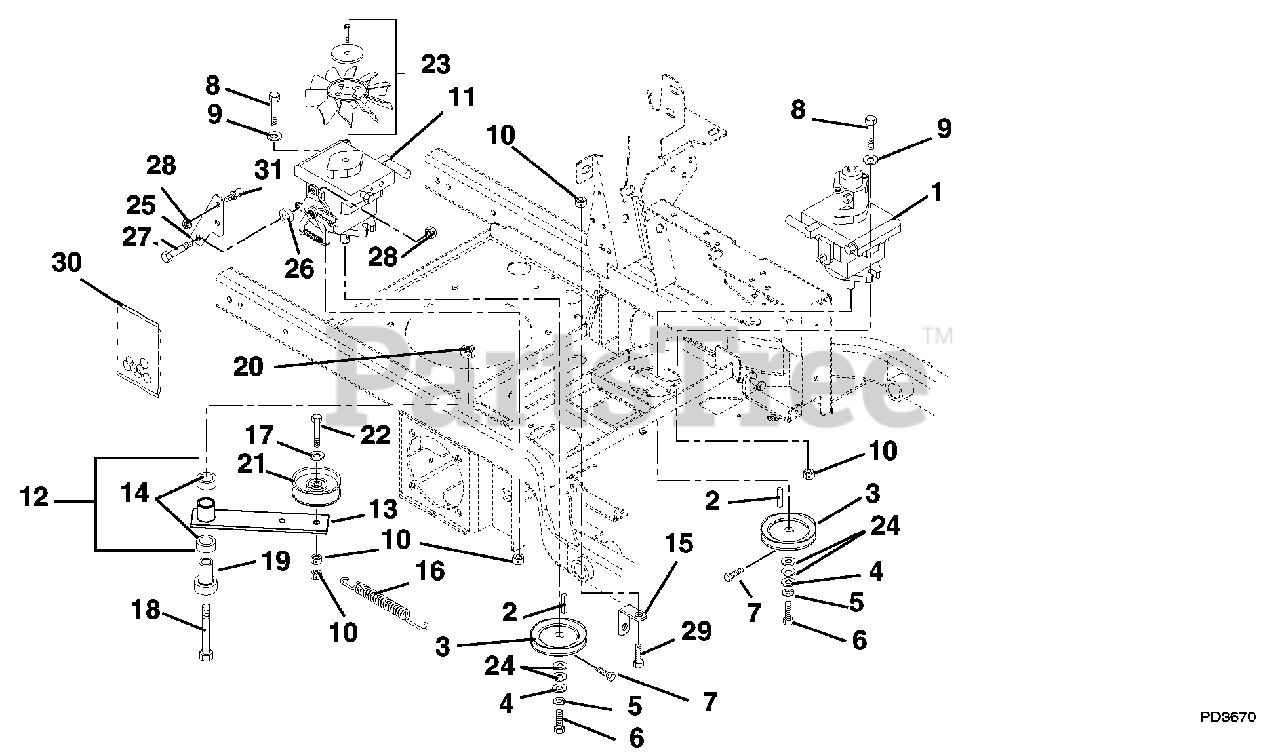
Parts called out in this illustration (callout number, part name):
1	Hydrostat BDP with Auxiliary
2	Key, Straight 5mm x 25mm x 5mm
3	Sheave 4.0 x .199
4	Washer, Flat Steel .281 x 1.00 x .063
5	Washer, Locking .25 x .062
6	Bolt, Hex M6 x 1.0 x 12
7	Bolt, Hex .25-20 x .50 Grade 5
8	Bolt, Hex .38-16 x 1.25 Grade 5
9	Washer, Flat Steel .39 x .75 x .125
10	Nut, Locking Top Flange .38-16
12	Assembly,Idler Arm Guard Drive
13	Weldment, Idler Arm Ground Drive
14	Bearing, 1.00 x 1.12 x .75
15	Anchor, Idler Spring
16	Spring, Tension .120 x .845 x 6.50
17	Washer, Flat Steel .39 x.75 x.125
18	Bolt, Hex .50-13 x 3.50 Grade 5
19	Bearing, Pedestal Powdered Metal
20	Nut, Locking Top Flange .50-13
21	Idler, Flat 4.00 x 1.06
22	Bolt, Hex .38-16 x 2.25 Grade 5
23	Fan, Cooling
24	Washer, Flat Steel .656 x 1.31 x .095
25	Bracket, Return to Neutral/Damper
26	Spacer .344 x 1.00 x .375
27	Bolt, Hex .31-18 x 1.25 Grade 5
28	Nut, Locking Top Flange .31-18
29	Bolt, Hex .38-16 x .75 Grade 5
30	Kit, Pump Seal (BDP-10A)
31	Stud, Ball
